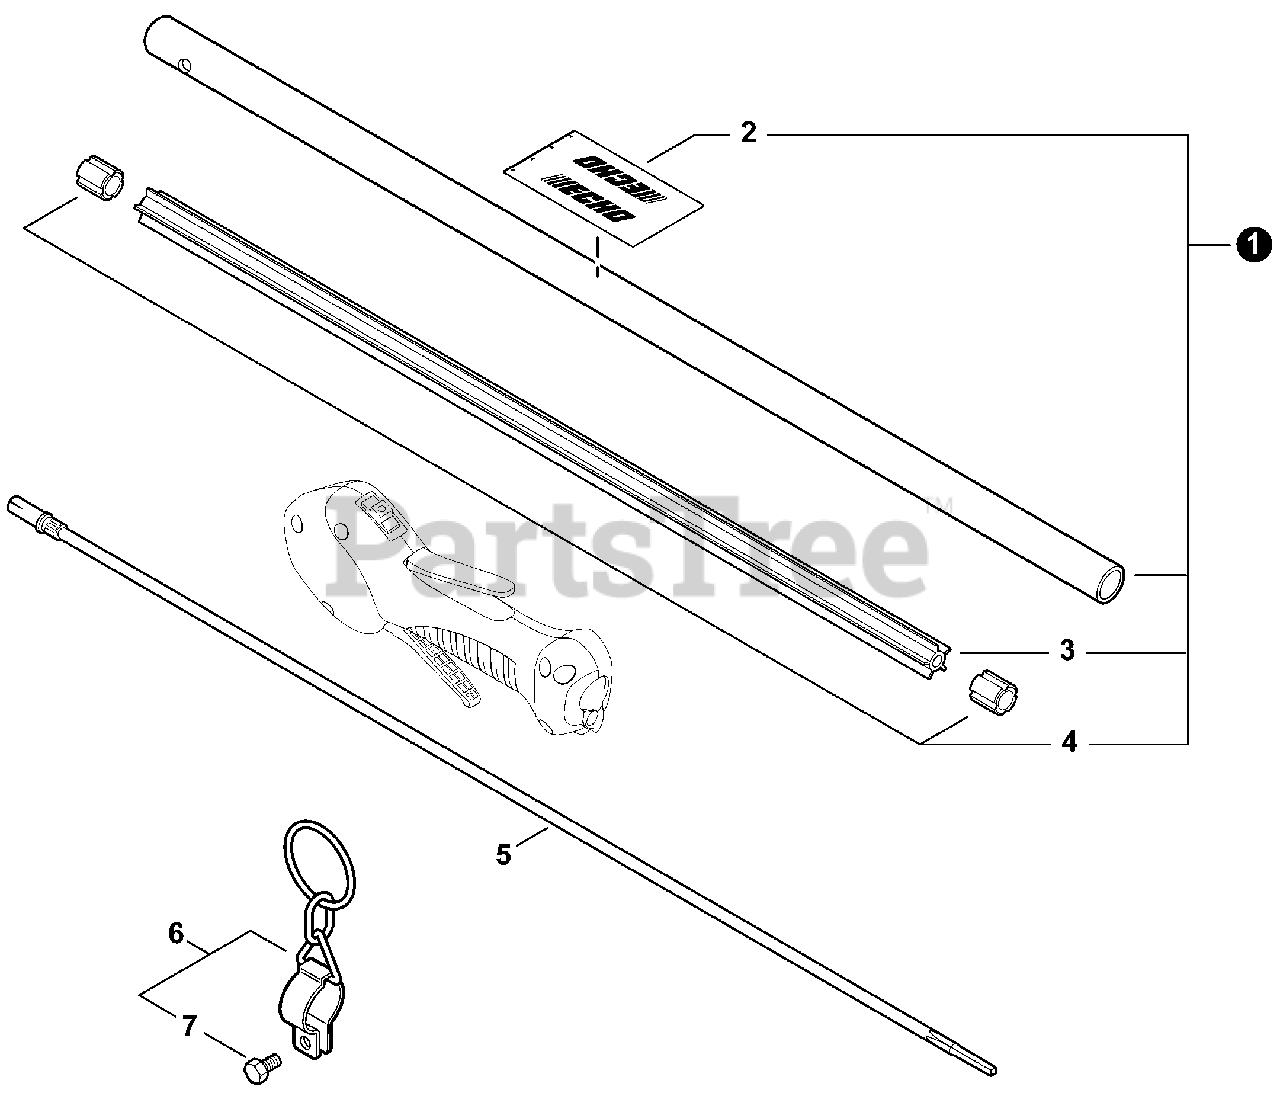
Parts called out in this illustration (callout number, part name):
1	MAIN PIPE ASSY
2	LABEL, HANDLE LOCATION
3	LINER - FLEXIBLE
5	DRIVESHAFT - FLEXIBLE
6	HANGER SET, HARNESS
7	BOLT, TORX 5×12
